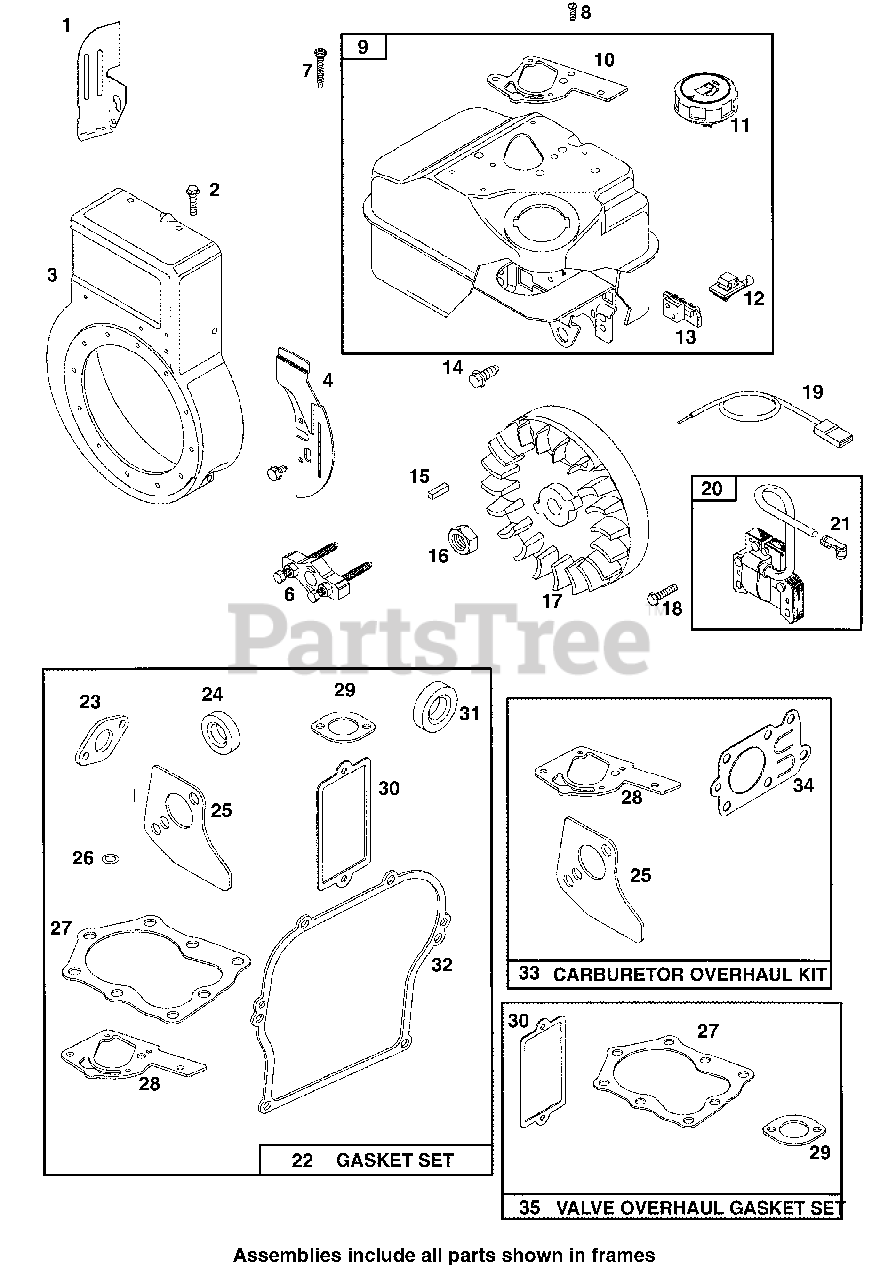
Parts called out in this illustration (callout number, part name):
2	Hex Screw
3	Blower Housing
4	Flywheel Guard
6	Flywheel Puller
7	Torx Screw
8	Torx Screw
9	Fuel Tank
10	Fuel Tank Gasket
11	Fuel Tank Cap
12	Stop Switch
13	Governor Gear Rack
14	Hex Screw
15	Flywheel Key
16	Flywheel Nut
18	Hex Screw
19	Stop Wire
20	Magneto Armature
21	Cable Terminal
22	Gasket Set
23	Exhaust Gasket
24	Oil Seal
25	Intake Gasket
26	Seal-O-Ring
27	Cylinder Head Gasket
28	Fuel Tank Gasket
29	Air Cleaner Gasket
30	Breather Gasket
31	Oil Seal
32	Crankcase Gasket
33	Carburetor Kit
34	Carburetor Diaphragm
35	Valve Overhaul Kit
